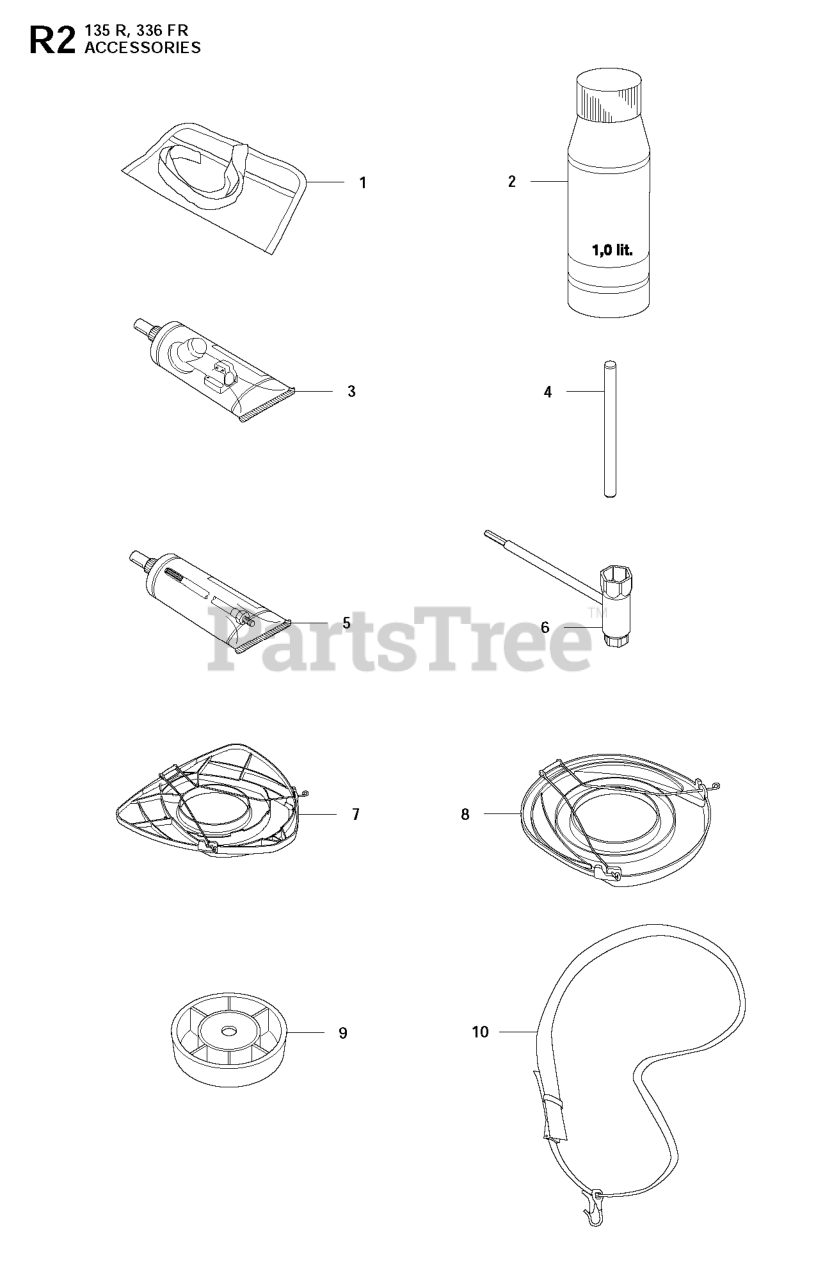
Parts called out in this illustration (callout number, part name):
2	Air Filter Oil 1l.
4	LOCKING PIN
5	DRIVE SHAFT GREASE (200 G)
6	COMBINATION WRENCH
7	TRANSPORT GUARD
8	BLADE GUARD TRANSPORT
9	SUPPORT CUP
10	Harness-w/o warning
10	Harness - Diagonal with sign
